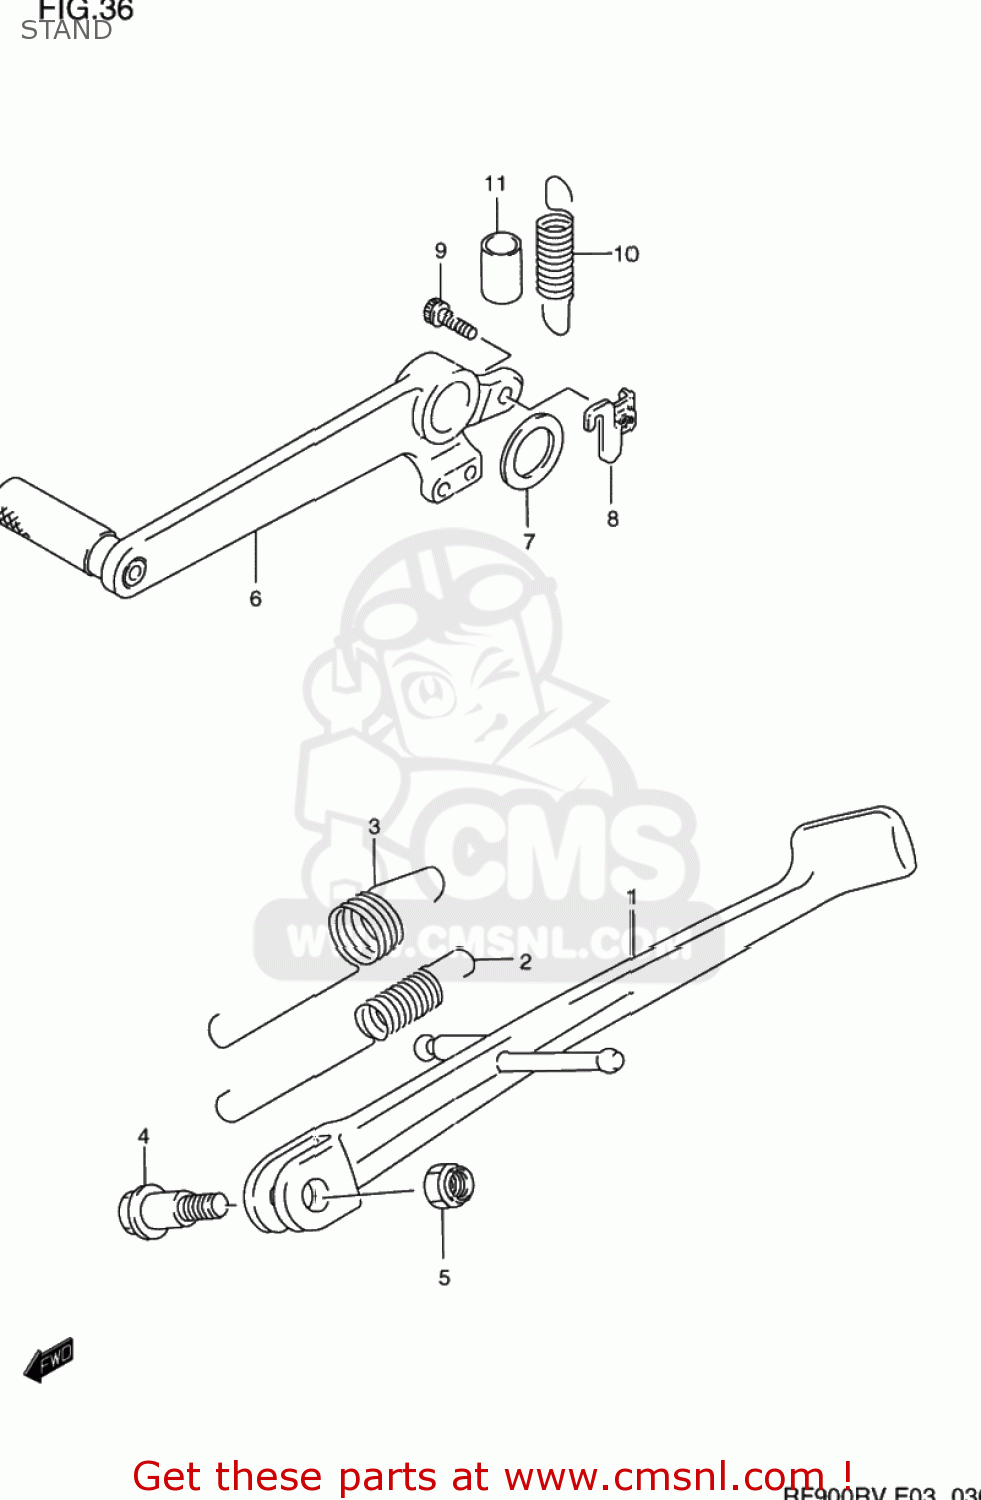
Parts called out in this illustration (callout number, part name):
1	STAND,PROP
2	SPRING
3	SPRING
4	BOLT(10X34)
5	NUT
6	PEDAL,BRAKE
7	WASHER(18X24X1)
8	BRACKET,STOP LAMP SWITCH SPR
9	BOLT
10	SPRING
11	TUBE,BRAKE SPRING GUIDE
